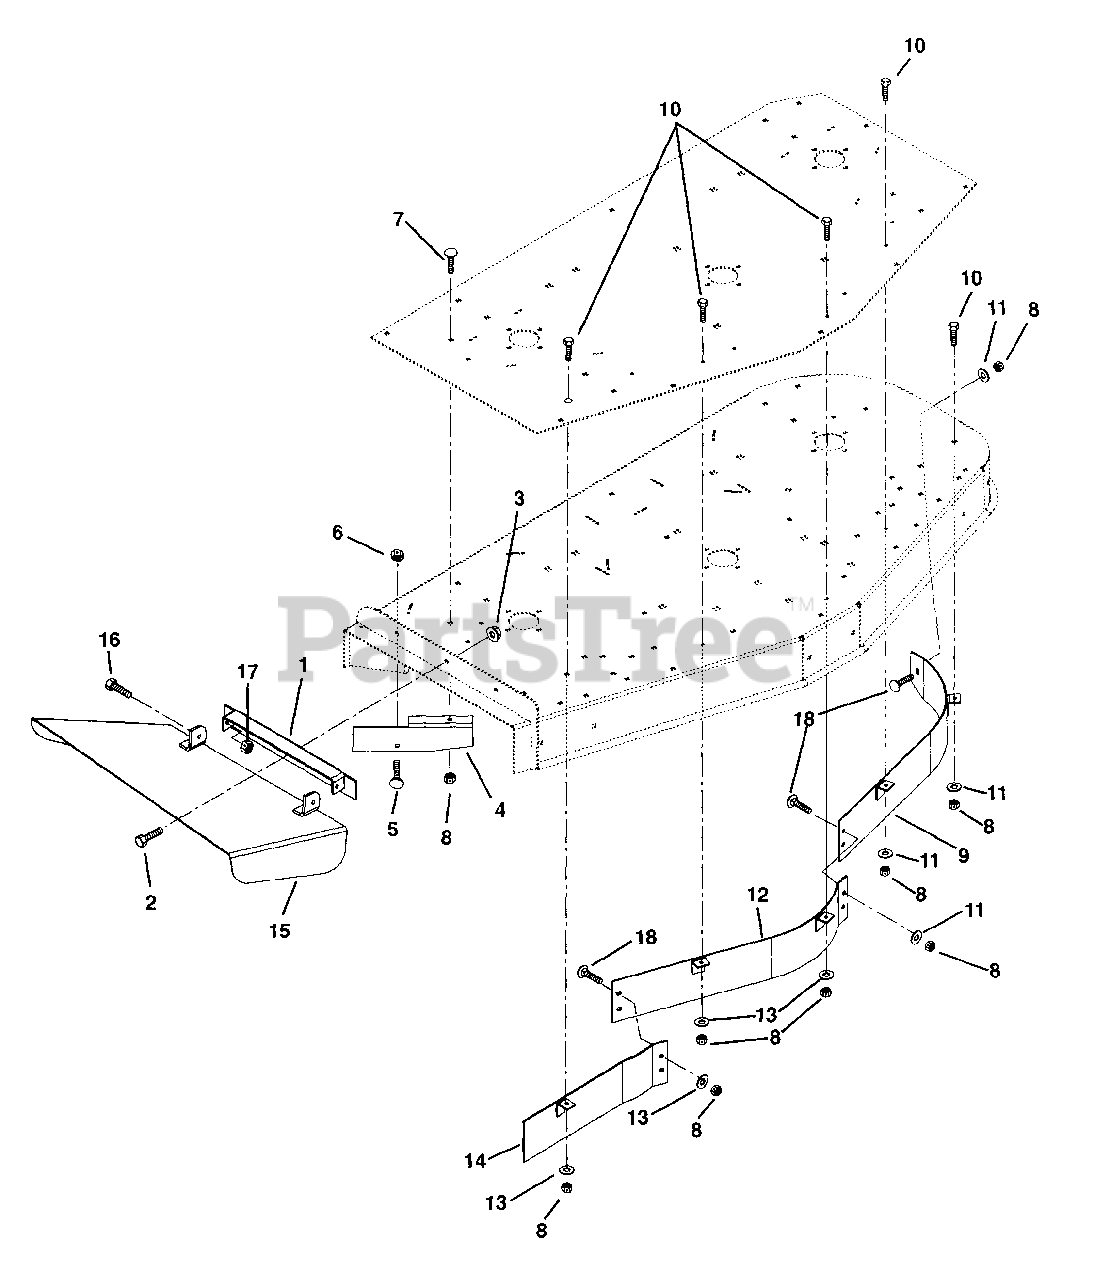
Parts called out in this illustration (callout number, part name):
1	Weldment, Discharge Chute Bracket
2	Bolt-Hex .38-16 x 1.00 Grade 5
3	Nut-Locking-Flange .38-16
4	Deflector, 60"
5	Bolt-Round Head Square Neck .38-16 x 1.00 Grade 2
6	Nut-Locking-Center .38-16
7	Bolt-Round Head Square Neck .31-18 x 1.00 Grade 5
8	Nut-Locking-Nylon .31-18
9	Weldment, 60" Left Hand Baffle-Upper
10	Bolt-Hex .31-18 x 1.00 Grade 5
11	Washer-Flat-Steel .312 x .734 x .065
12	Weldment, 60" Center Baffle-Up
13	Washer-Flat-Steel .312 x .734 x .065
14	Weldment, 60" Right Hand Baffle-Upper
15	Weldment, Discharge Chute 60"
16	Bolt-Hex .38-16 x 1.00 Grade 5
17	Nut-Locking-Center .38-16
18	Bolt-Round Head Square Neck .31-18 x .75 Grade 2
19	60" Mulching Kit
20	60" Discharge Cover
